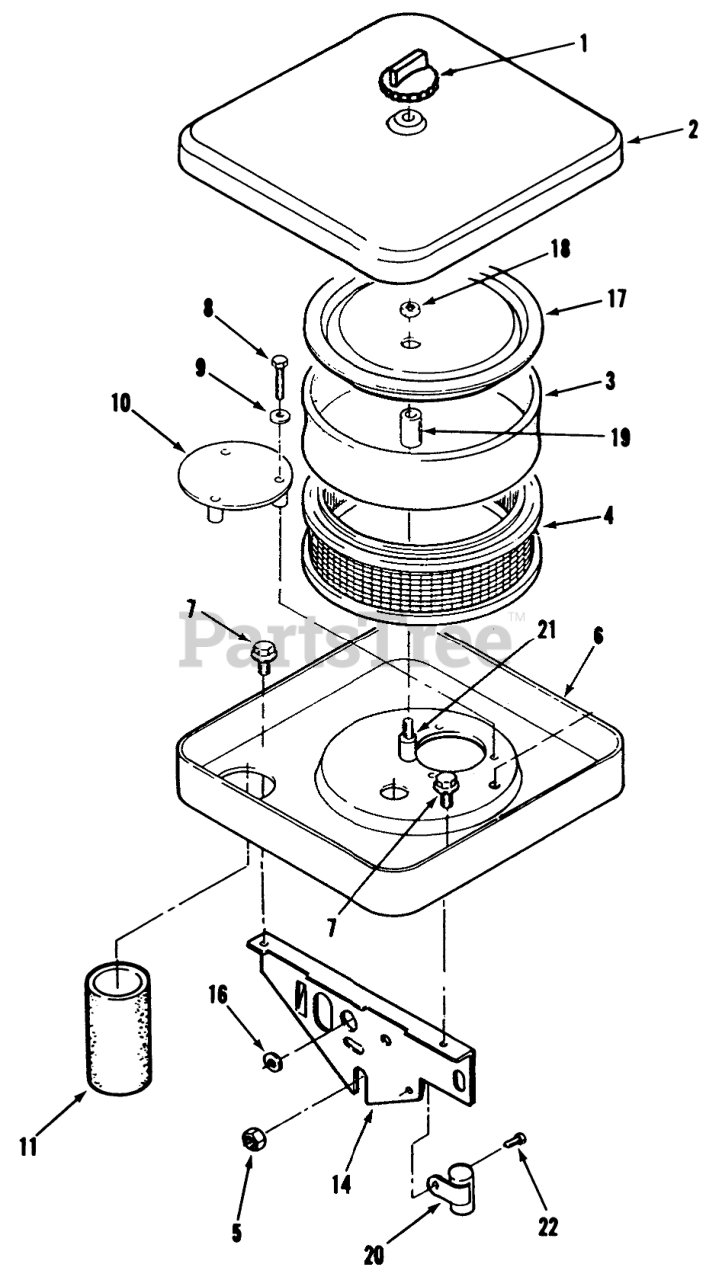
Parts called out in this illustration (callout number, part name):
1	KNOB-TOOL LESS
2	AIR-CLEANER COVER
3	AIR CLEANER ELEMENT
4	Stationary Guard
5	Nut
6	AIR-CLEANER HOUSING
7	Screw 1/4-20 x 3/8
8	Screw Hex Hd. #10-32 x 1-1/2
9	Flat Washer #10
10	AIR DEFLECTOR PLATE
11	AIR INTAKE TUBE
14	SUPPORT-AIR CLEANER
16	Grommet
17	Element Cover
18	Hex Nut 1/4-20
19	Spacer
20	Condenser
22	SCREW #10-32 X 5/8
